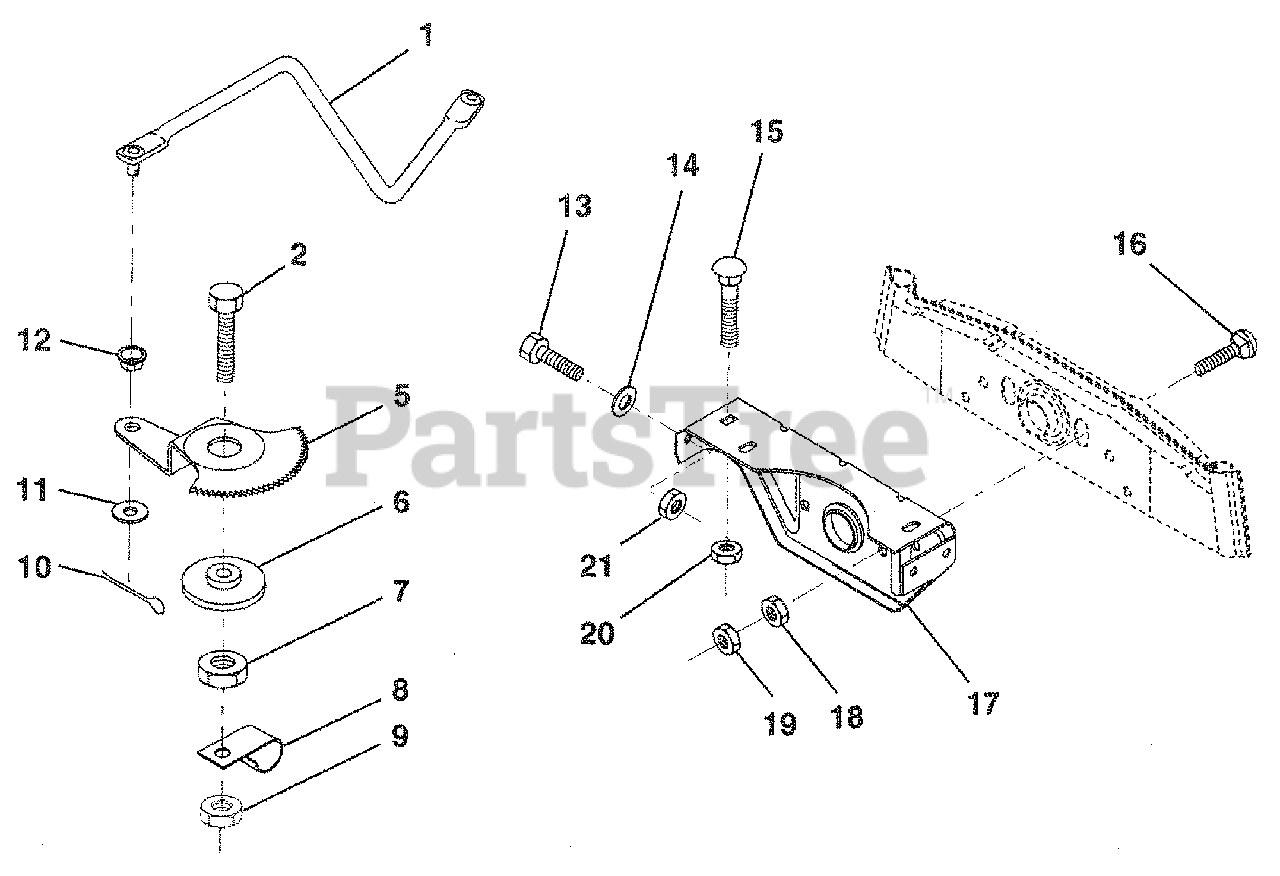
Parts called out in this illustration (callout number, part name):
1	Link, Drag
2	Bolt, Fin Hex 1/2-13 x 1-3/4
5	Gear, Sector
7	Nut, Heavy Hex Top Lock 1/2-13 UNC
8	Clip, Insulated
9	Nut, Crownlock 3/8-16
10	Pin, Cotter 1/8 x 3/4
11	Washer, 13/32 x 13/16 x 16 Ga.
13	Bolt, Hex Hd. 5/16-18 UNC x 1
14	Washer 11/32 x 7/8 x 16 Ga.
15	Bolt, Carriage 3/8-16 UNC x 3/4
16	Bolt, Carriage
17	Support, Front Axle
18	Nut, Fin Hex 3/8-16 UNC
19	Nut, Centerlock 3/8 - 16 UNC
20	Nut,Crownlock 3/8-16UNC
21	Nut, Crowniock 5/16-18
